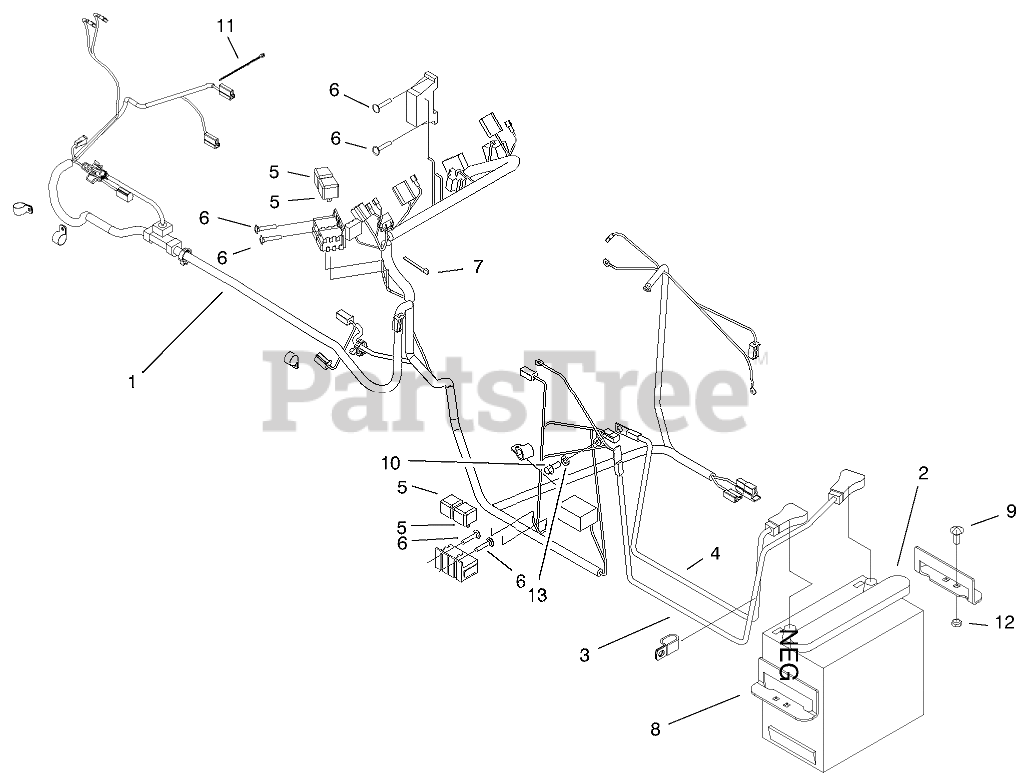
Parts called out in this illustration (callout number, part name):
1	Harness-Main
2	BATTERY - 495CCA
3	CABLE - BATTERY,RED
4	CABLE - BATTERY,
5	RELAY
6	SCREW
7	TIE-CABLE
8	HOLD - DOWN, BATTERY
9	SCREW-CARR
10	SCREW-HH
11	TIE-CABLE
12	NUT-LOCK, NI
13	WASHER-LOCK
